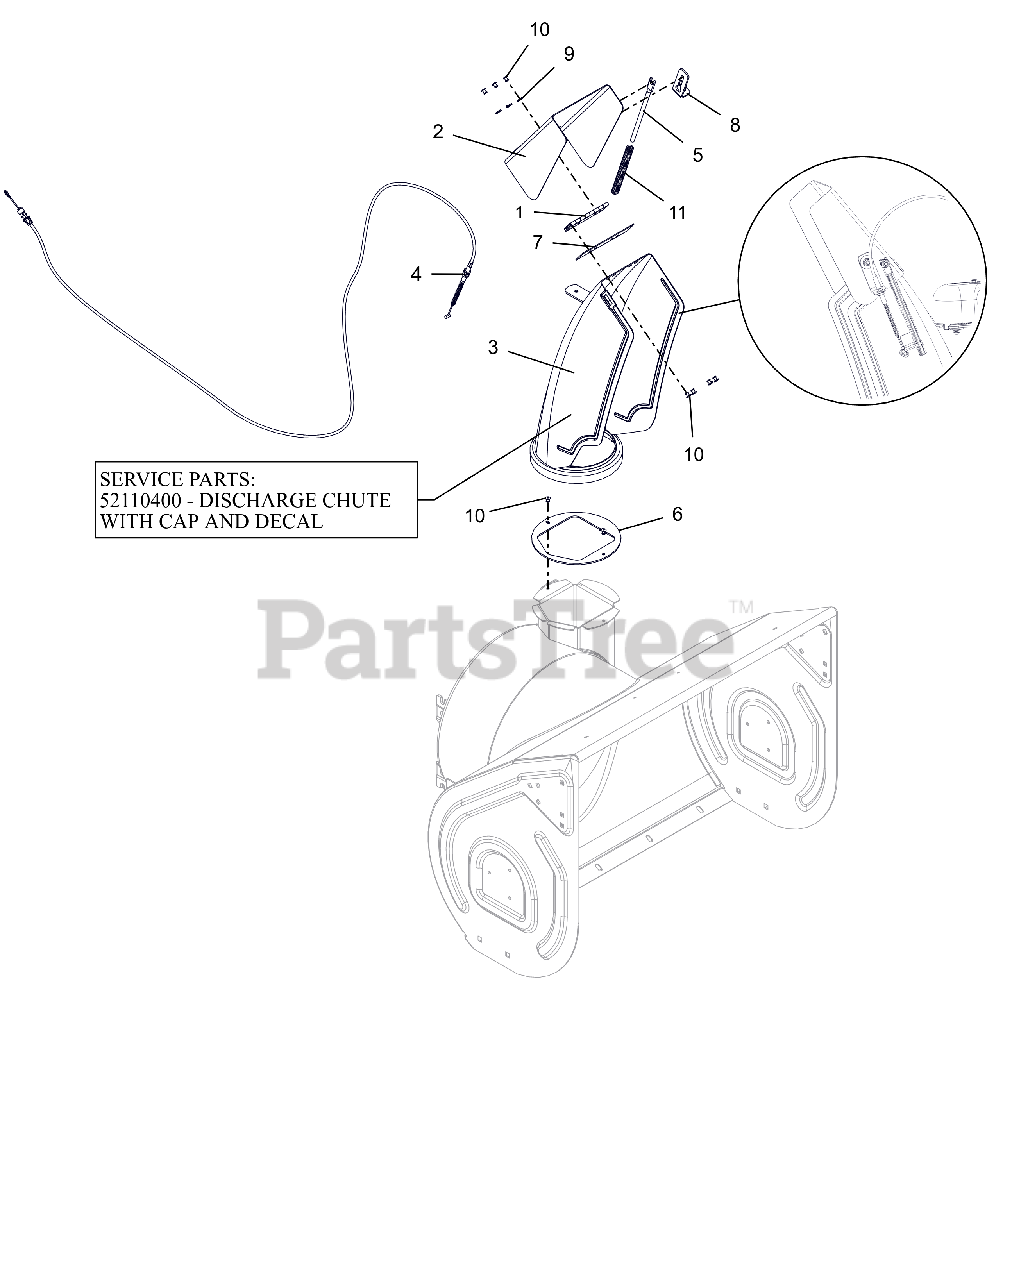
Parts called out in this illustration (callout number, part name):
2	CAP, LARGE REMOTE W/DECAL
3	CHUTE,DISCHARGE,NOTCHED,QT
3	CHUTE, DISCHARGE W/CAP
4	CABLE, DEFLECTOR - DELUXE
5	ROD, DEFLECTOR CAP
6	BAFFLE, DISCHARGE NECK
7	CAP SEAL 5.50
8	BRACKET, ANCHOR-CHUTE CABLE
9	WSHR,FLT .196X.500X.066 ZCC
10	RVT, POP .1875 ZCC
11	SG-COMP .08X.40X6.50 14#/IN
